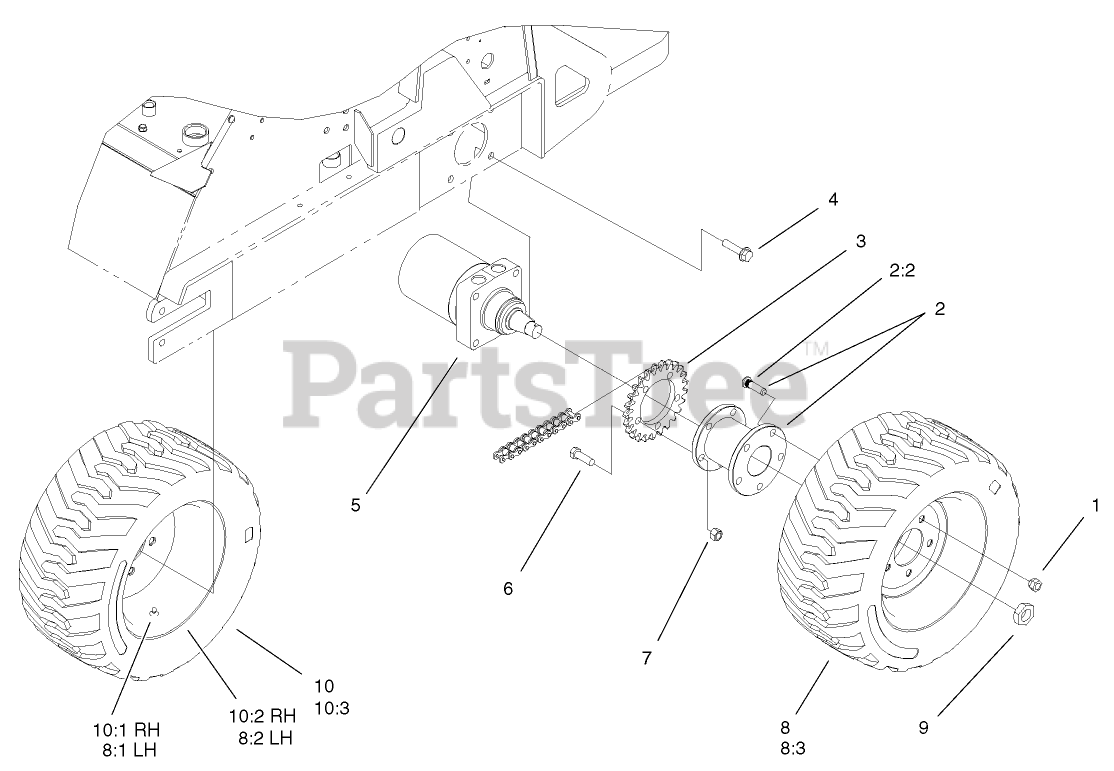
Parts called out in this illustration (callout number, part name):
1	NUT-LUG
2	REAR HUB ASM
2:2	STUD-TYPE, DRIVE
3	SPROCKET-25T
4	SCREW-HHF
5	HYD MOTOR ASM
6	SCREW-HH
7	NUT-LOCK, NI
8	LH WHEEL AND TIRE ASM
8:1	STEM-VALVE
8:2	WHEEL
9	NUT-LOCK
10	RH WHEEL AND TIRE ASM
10:1	STEM-VALVE
10:2	WHEEL
